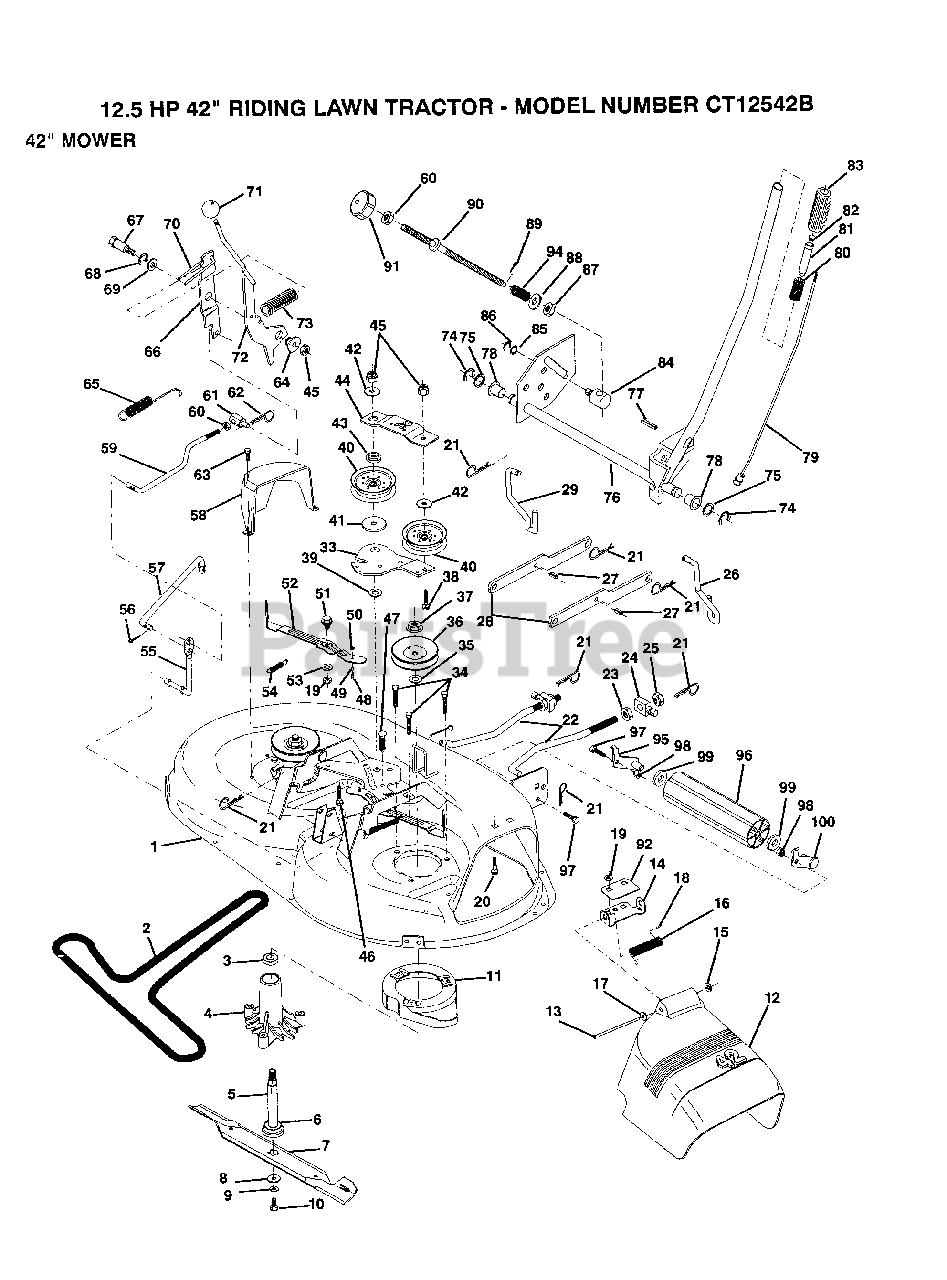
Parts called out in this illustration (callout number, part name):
2	BELT-V.92.4.MWR
3	BEARING
4	HSG ASM MANDREL
6	BEARING.BALL
8	WASHER BLADE
10	BLADE BOLT
12	DEFLECTOR.SHIELD
13	HINGE ROD
14	DEFLECTOR BRKT
15	NUT PUSH M
16	SPRING TORSION
17	WASHER
18	CAP-SLEEVE LT
20	BOLT
22	LINK.FRONT
23	NUT
24	TRUNION
25	NUT.LK.W/WSH.1/2.
26	LIFT LINK RH
27	SPRING PIN
29	LINK LIFT LH
33	IDLER ARM
35	WASHER
38	BOLT
39	HARDENED WASHER
40	FLAT IDLER PULLEY
41	SPACER RETAINER
42	WASHER GT
43	RETAINER SPACER
44	IDLER ARM STIFF
46	BOLT CARRIAGE
47	XMAS TREE FASTNER
48	SHOULDER BOLT
50	LOCKNUT
52	BRAKE PAD ARM ASM
53	HARD SMALL WASHER
54	SPRING EXTENSION
55	PIVOT ROD
57	CLUTCH ROD SECOND
60	NUT
61	TRUNION
62	RETAINER M
63	SCREW LT
64	BUSHING
65	RETURN SPRING
66	CLUTCH ARM SECOND
67	SHOULDER BOLT
68	RING
69	WASHER
70	SPRING KEEPER
72	CLUTCH ARM PRI AS
75	WASHER
77	PIN-GROOVE LT
78	NYLON BEARING
82	BUTTON PLUNGER YELLOW
83	GRIP
84	TRUNION LT
85	WASHER
86	KLIP RING
87	NUT T
88	WASHER
92	STIFFENER BRKT
94	SPRING T
97	BOLT
99	WASHER
